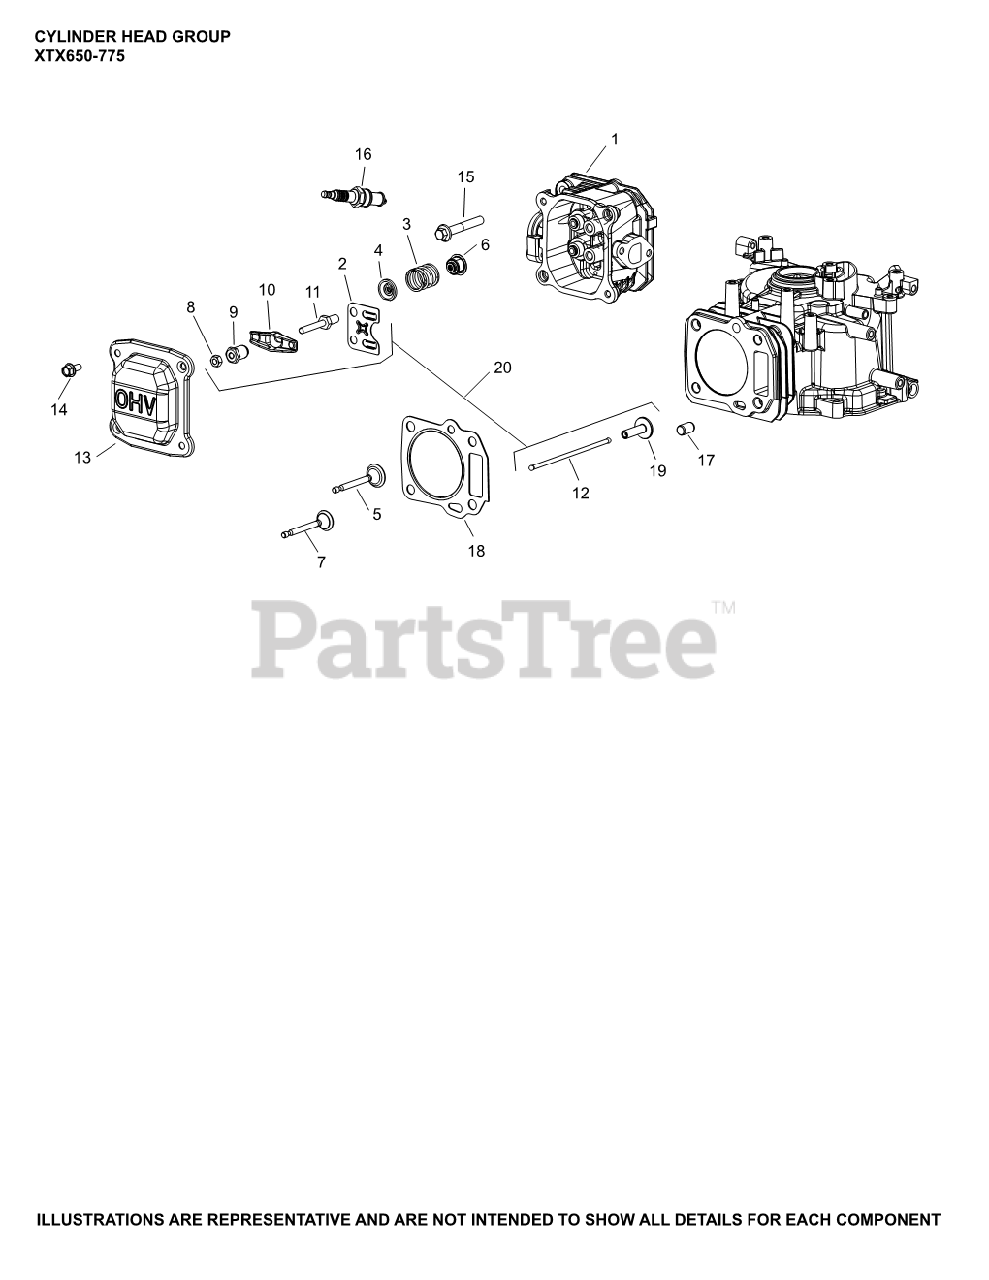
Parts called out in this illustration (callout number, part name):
1	HEAD, CYLINDER
2	PLATE, PUSHROD GUIDE
3	SPRING, VALVE
4	RETAINER, VALVE SPRING
5	VALVE, INTAKE
6	SEAL, VALVE STEM
7	VALVE, EXHAUST
8	NUT, HEX JAM
9	PIVOT, ROCKER ARM
10	ARM, ROCKER
11	STUD, ROCKER ARM
12	ROD, PUSH
13	COVER, VALVE
14	SCREW, HEX FLANGE (M6)-USE 25 086 433-S
15	SCREW, HEX FLANGE M8
16	PLUG, SPARK 12MM RFI
17	DOWEL, CYLINDER HEAD-(#1438013S)
18	KIT, HEAD GASKET USE 14 841 34-S
19	LIFTER, VALVE
20	KIT, VALVE TRAIN
